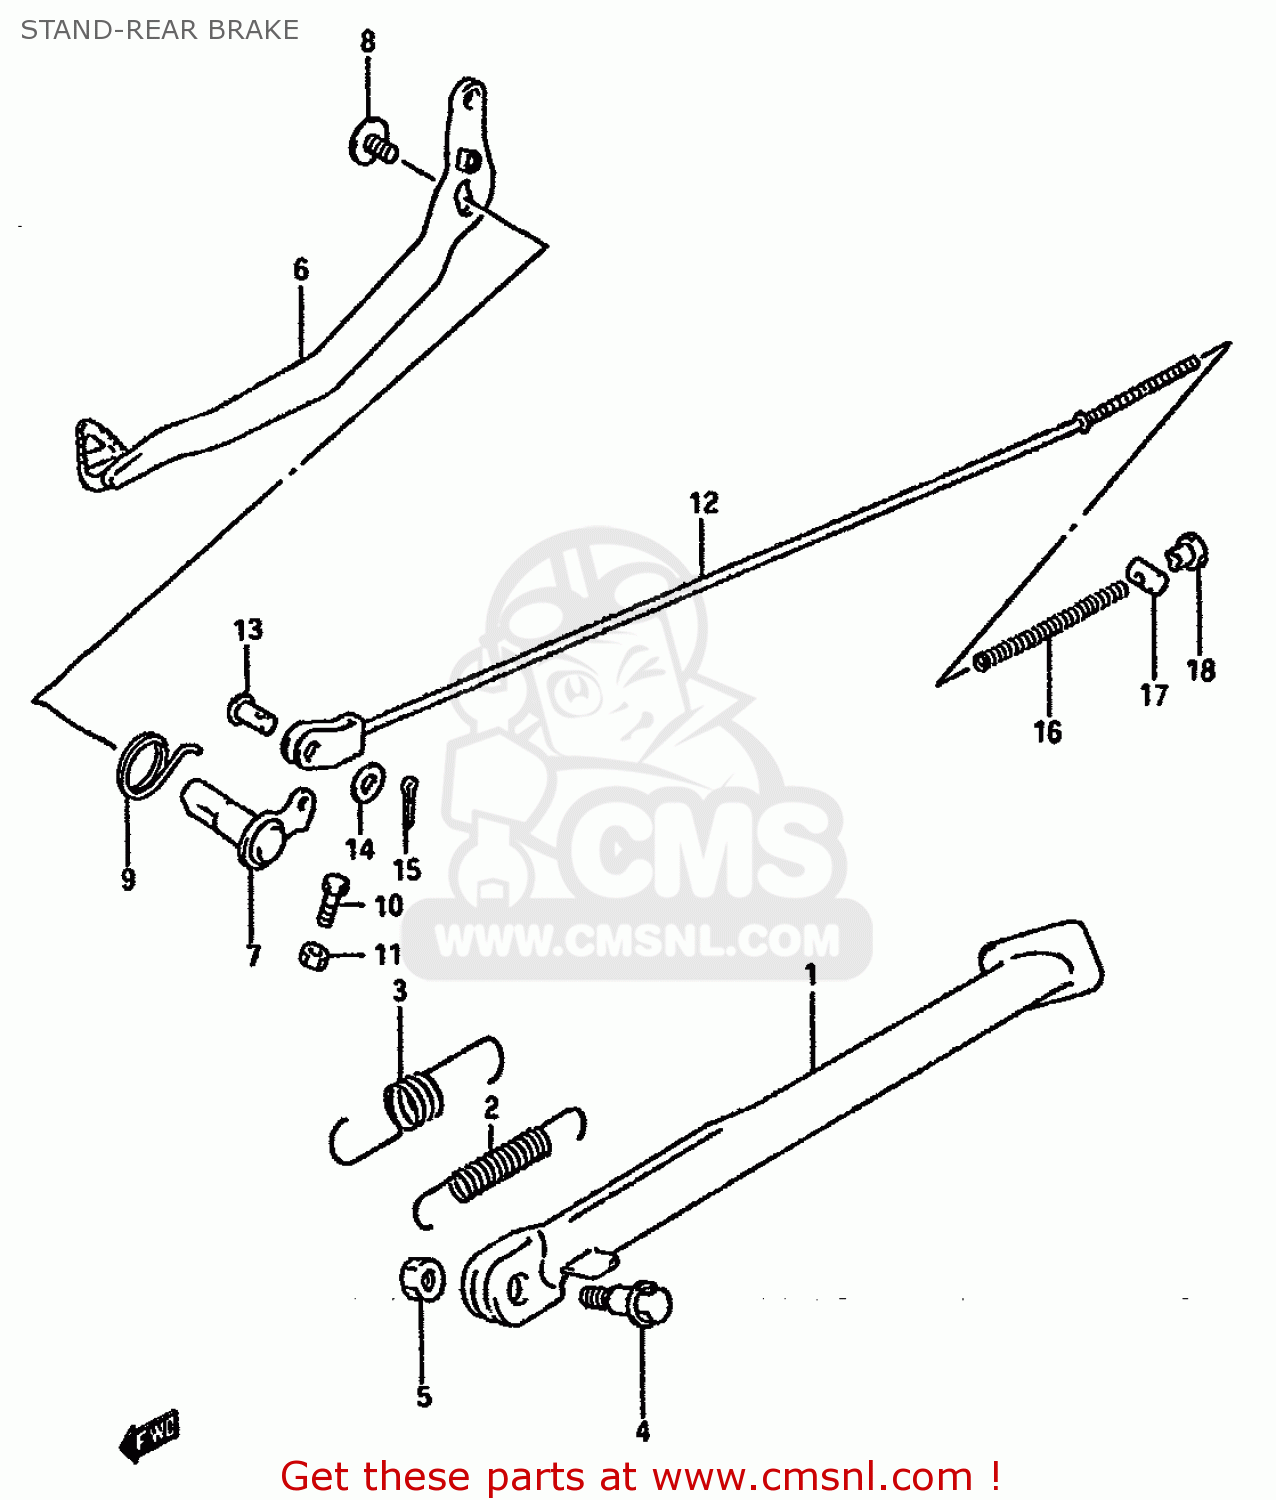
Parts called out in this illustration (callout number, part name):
1	STAND,PROP (BLUE)
2	SPRING
3	SPRING
4	BOLT(10X33.5)
5	NUT
6	PEDAL,BRAKE
7	ARM,BRAKE PEDAL ROD
8	BOLT 8X14
9	SPRING
10	BOLT(6X23)
11	NUT 6MM
12	ROD ASSY,REAR BRAKE
13	PIN
14	WASHER
15	PIN 20X20
16	SPRING
17	PIN(11X18)
18	NUT (6MM)
